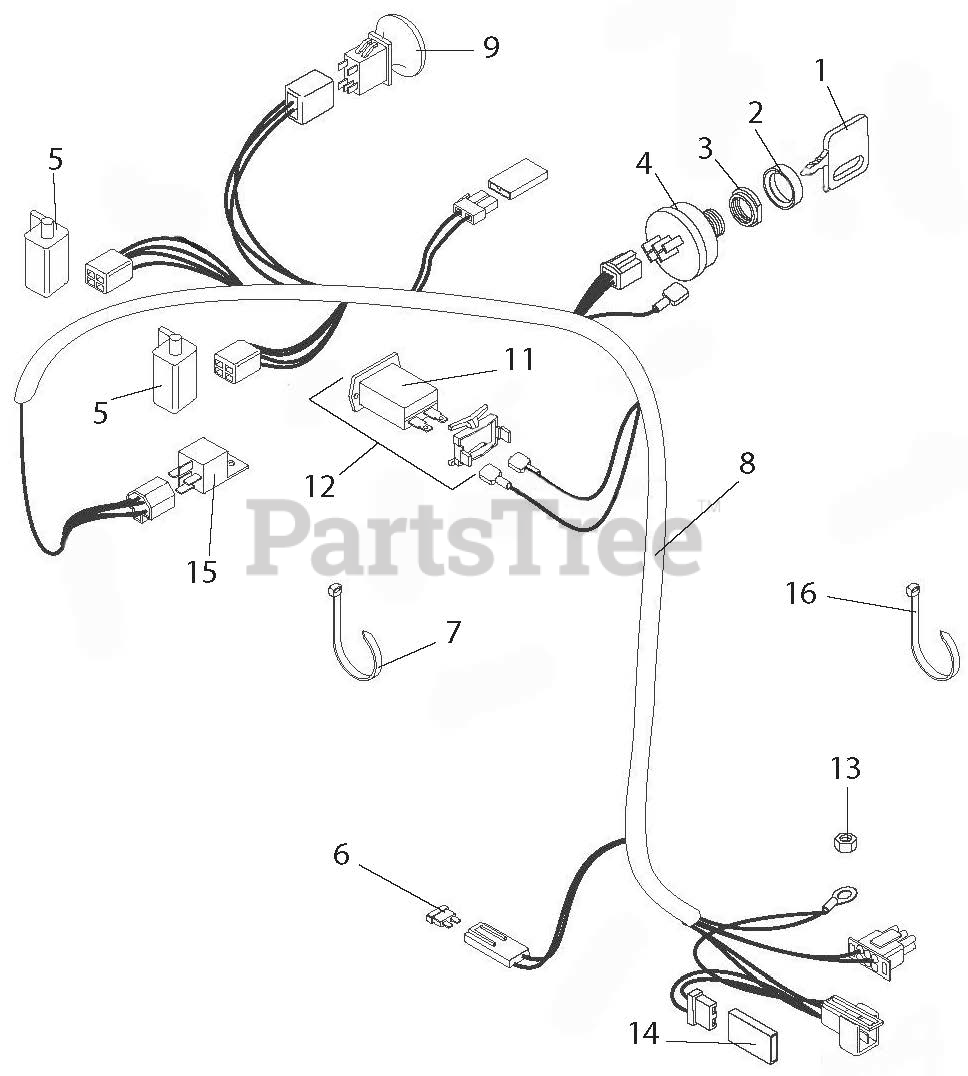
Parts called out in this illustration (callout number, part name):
1	Key- with Cap
2	Cap, Ignition Switch
3	Nut, Panel .562-24
4	Key Switch
5	Switch- Double Pole N.O./N.O.
5	Switch- Single Pole N.O.
6	Fuse-25 AMP
7	Tie Wrap-Black
8	Harness, Wire Gear Recoil-Pro Steer
9	Switch, Clutch
10	Module, Interlock Recoil
11	Hour Meter-Quartz
12	Kit, Hour Meter
13	Nut-Locking-Top-Flange .31-18
14	Diode, Connector Shell
15	Relay
16	Tie Wrap
